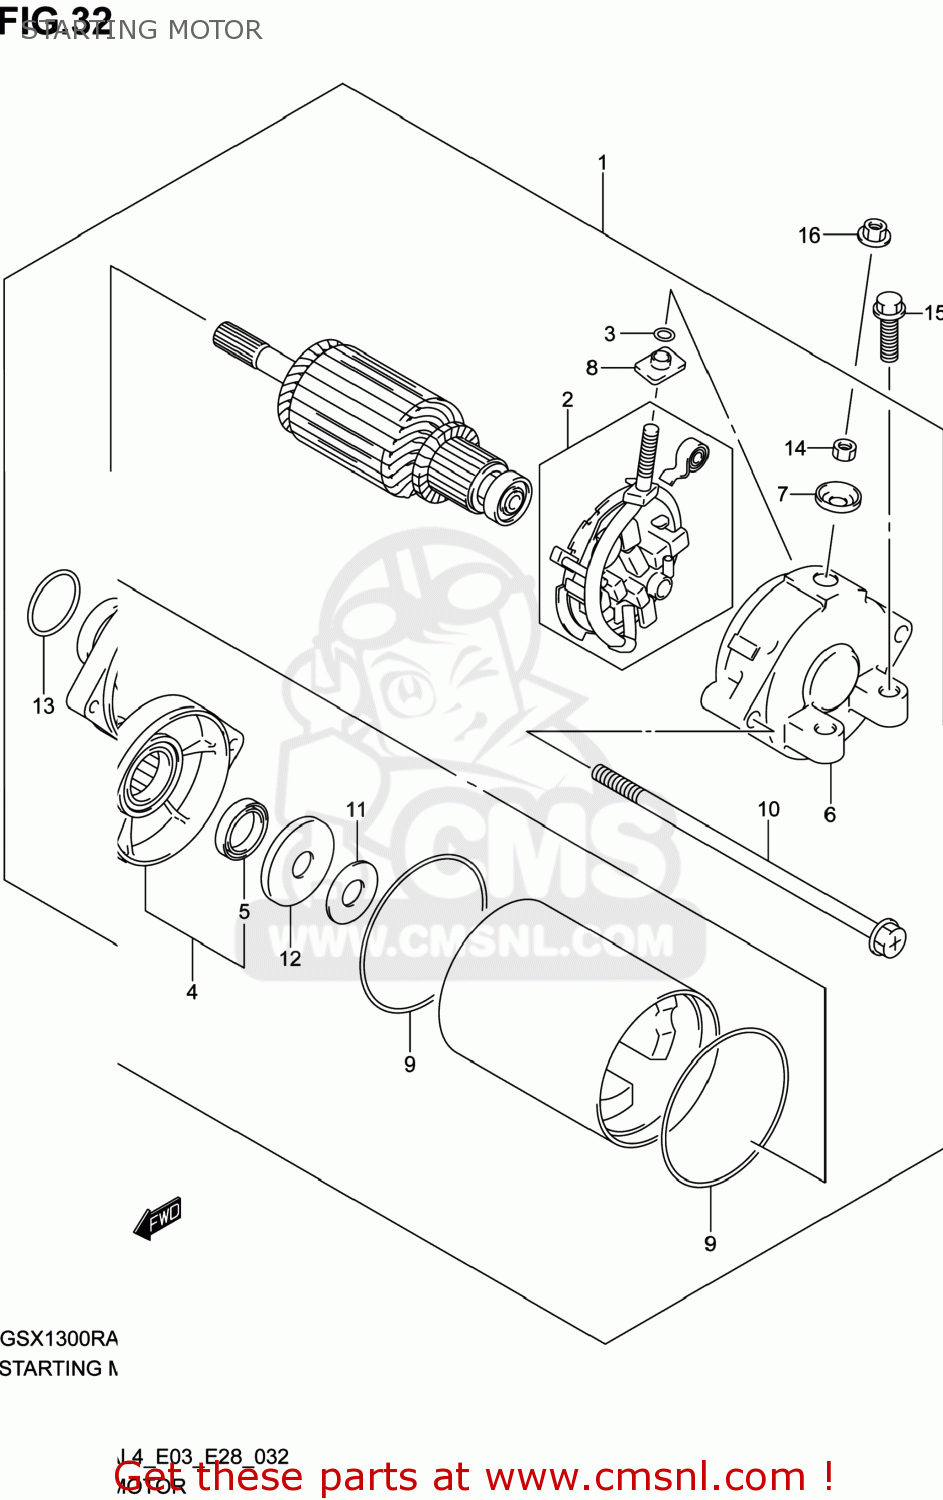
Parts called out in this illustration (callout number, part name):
1	MOTOR ASSY,STARTING
2	HOLDER SET,BRUSH
3	O RING
4	HOUSING ASSY,STARTER
5	SEAL,OIL
6	FRAME,STARTER END
7	BUSHING
8	BUSHING
9	O RING
10	BOLT
11	SHIM
12	WASHER
13	O RING(D:3,ID:24.5)
14	NUT
15	BOLT(6X25)
16	NUT
